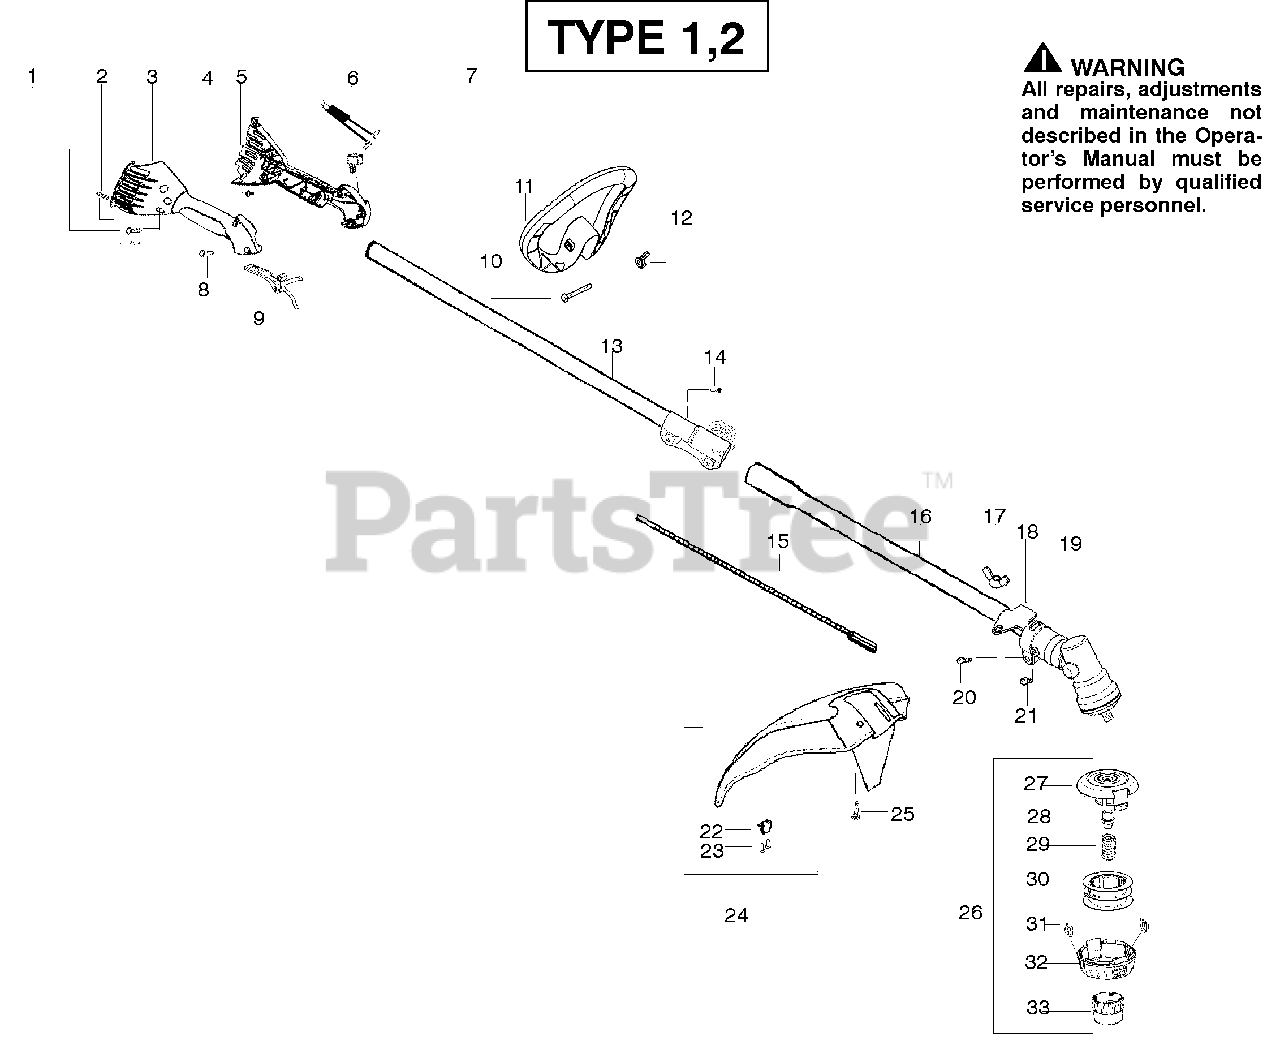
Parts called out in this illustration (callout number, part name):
1	Screw-alignment
3	Hsg.-Throttle right
4	Screw-Cable Retention
5	Hsg.-Left throttle
9	Lever-Throttle
11	Assy-Handle
12	Wingnut
13	Kit-Upper Shaft
15	Shaft-Flex (lower)
16	Kit-Lower Shaft
17	Wingnut
18	Bracket-Shield
24	Kit-Shield Assy.
26	Assy-TNG VII
28	Adapter
29	Spring
30	Accy-Wound Spool
31	Eyelet
32	Cover
33	Knob
